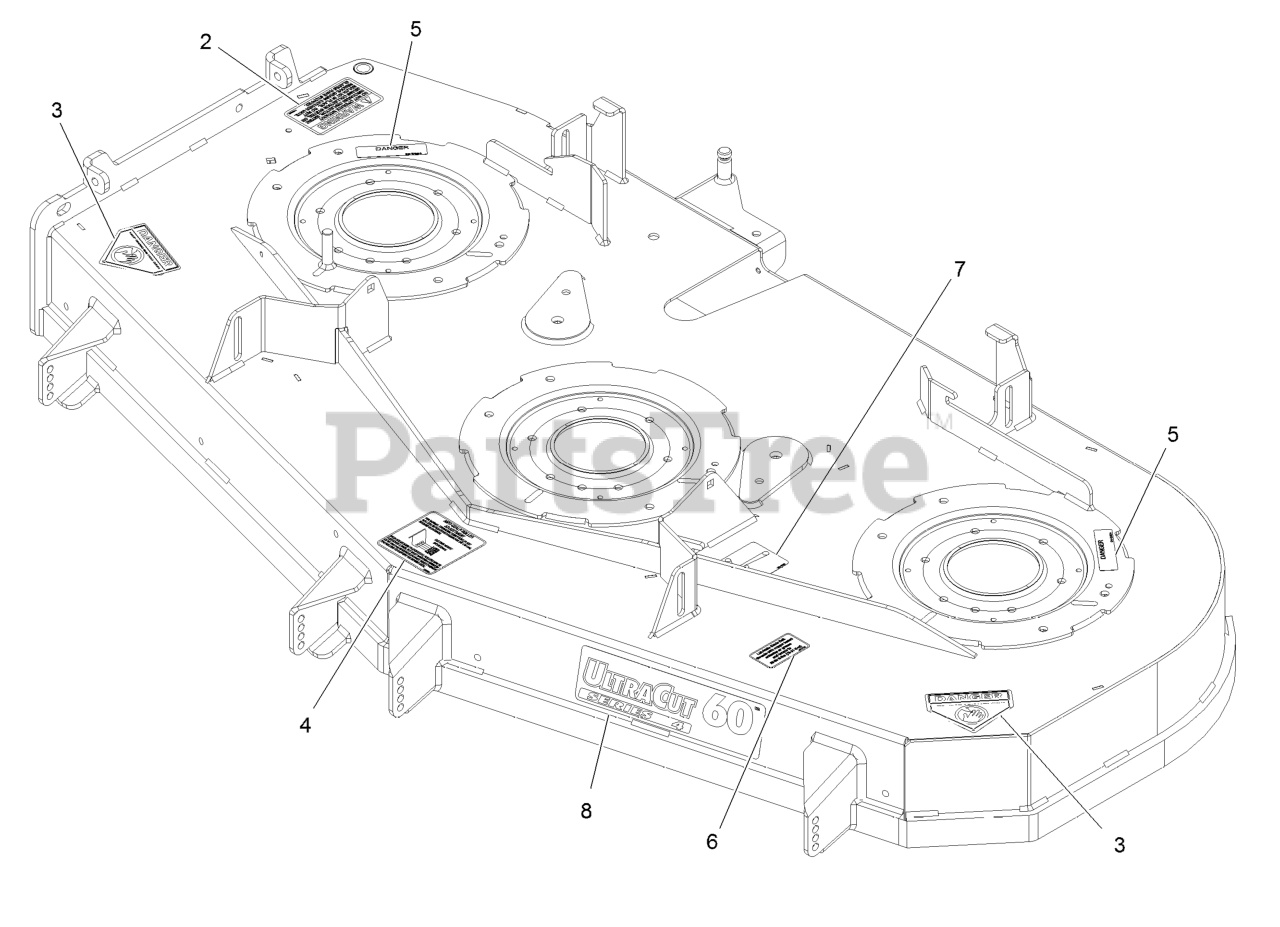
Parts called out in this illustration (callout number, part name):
2	DECAL-WARNING, DISCHARGE
3	DECAL-DANGER
4	DECAL,ANTISCALP
5	DECAL-COVER, MISSING
6	DECAL,BOLT TORQUE
7	DECAL-ROUTING, BELT
8	DECAL,ULTRACUT 60 SERIES
